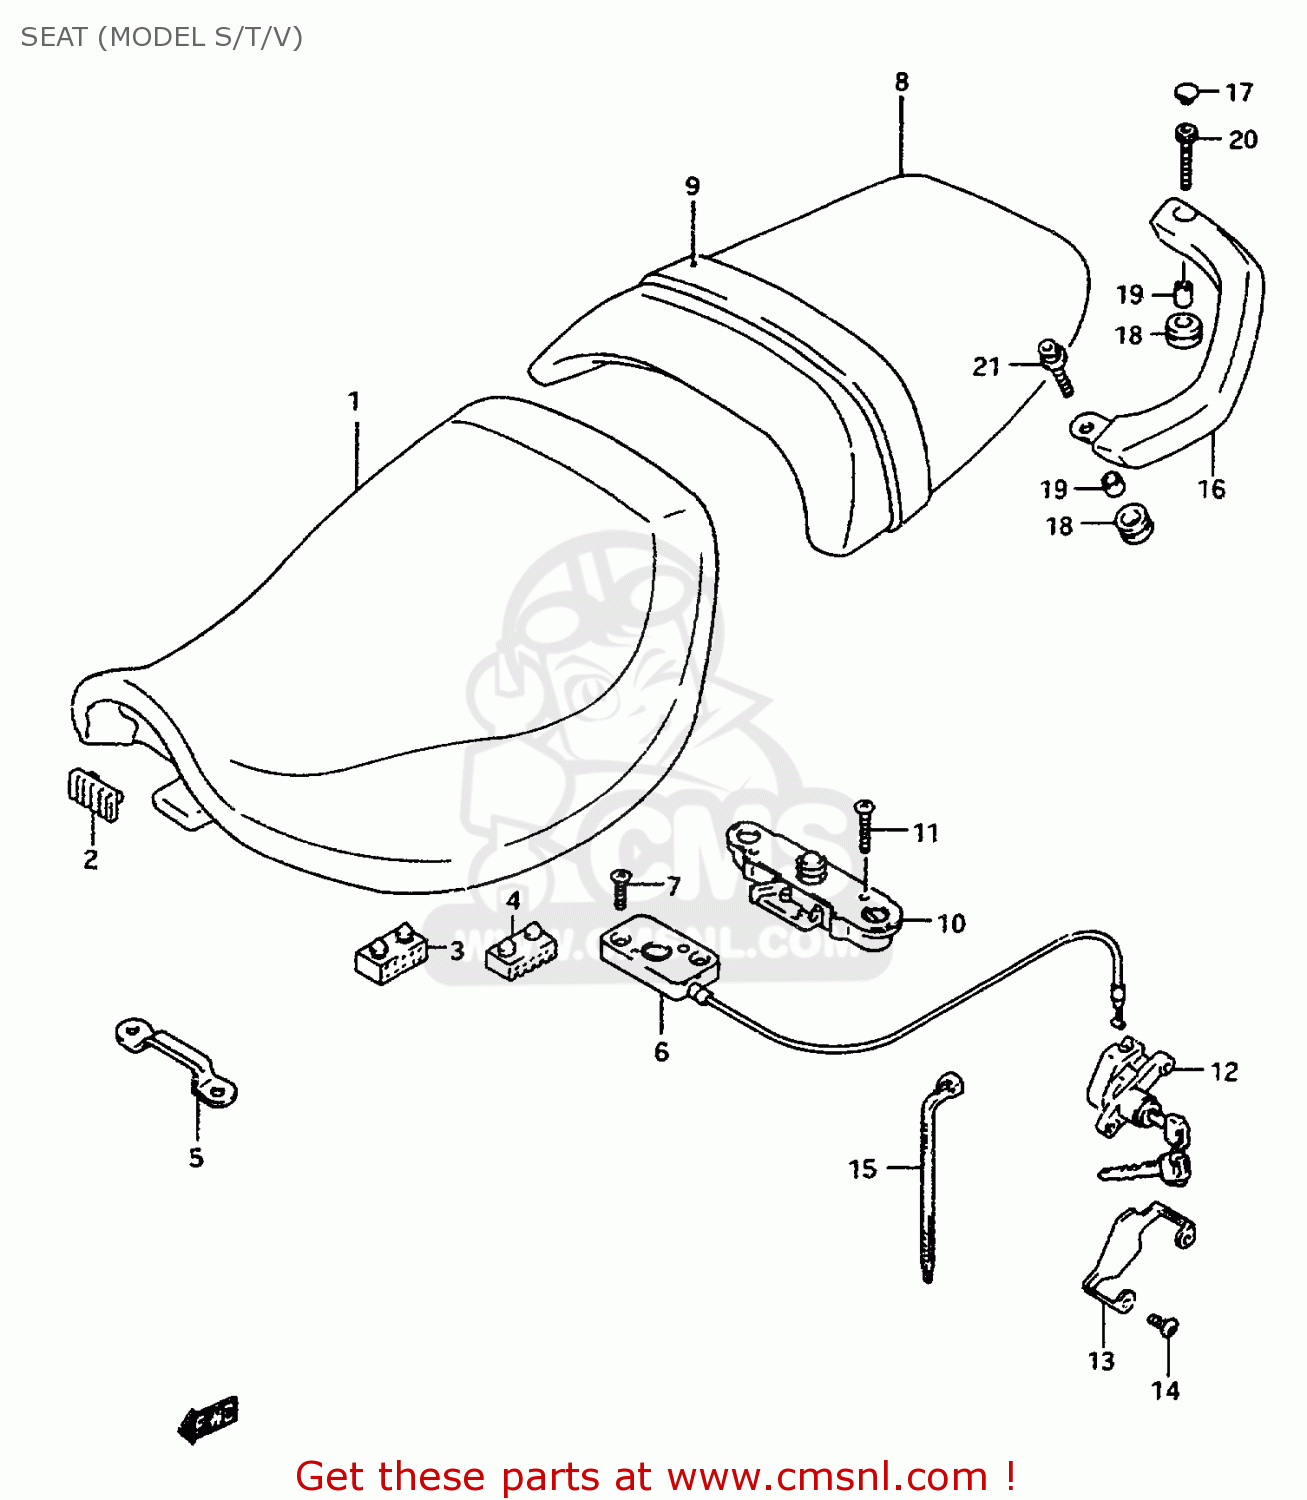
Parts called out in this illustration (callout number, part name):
1	SEAT ASSY
2	CUSHION,SEAT(40X20X6)
3	CUSHION,BATTERY
4	CUSHION,SEAT(40X20X15)
5	PLATE,SEAT FR HOOK
6	BRACKET COMP,SEAT SUPPORT
7	SCREW
8	SEAT ASSY,PILLION
9	BAND,SEAT (BLACK)
10	BRACKET COMP,SEAT SUPPORT
11	SCREW 6X30
12	LOCK SET,SEAT & HELMET
13	PLATE,SEAT LOCK GUARD
14	SCREW(6X12)
15	CLAMP(L:125)
16	HANDLE,PILLION RIDER,R(BLACK)
17	CAP(OD:14.5)
18	CUSHION
19	SPACER(8.4X12X12)
20	BOLT
21	BOLT
22	BAND
